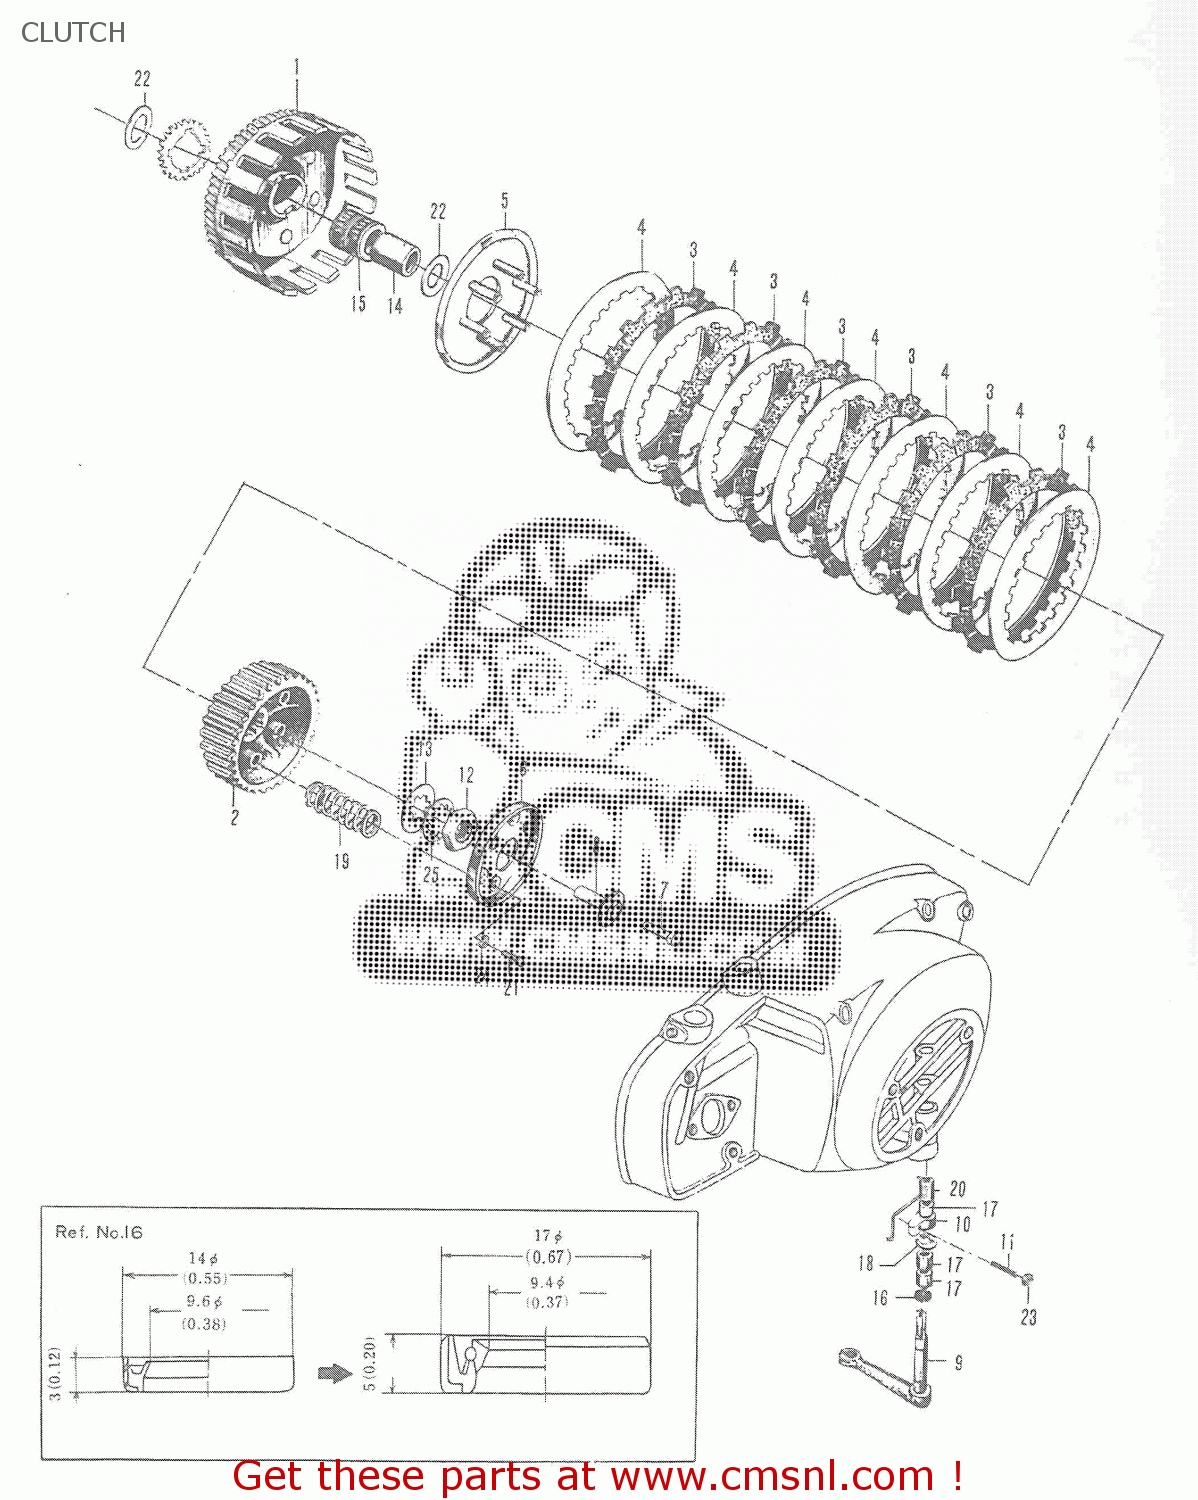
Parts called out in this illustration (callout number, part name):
1	CLUTCH HOUSING ASS'Y
2	CLUTCH SLEEVE HUB
3	CLUTCH CORK PLATE
4	CLUTCH STEEL PLATE
5	CLUTCH OUTER PLATE
6	C;UTCH PRESSURE PLATE
7	CLUTCH PUSH PIECE
8	CLUTCH PUSH PIECE
9	CLUTCH RELEASE ARM
10	CLUTCH RELEASE LEVER
11	CLUTCH RELEASE ADJUSTING SCREW
12	NUT (20MM)
13	CLUTCH SLEEVE HUB WASHER
14	CLUTCH HOUSING SPACER
15	PRIMARY DRIVEN GEAR BEARING 25X29X33.8
16	SEAL,OIL(10X17X5)
17	BUSHING
18	E-RING
19	CLUTCH SPRING
20	CLUTCH RELEASE ARM RETURN SPRING
21	CROSS HEAD SCREW
22	CLUTCH HOUSING THRUST WASHER
23	HEXAGON NUT
24	LOCK WASHER
25	LOCK WASHER
